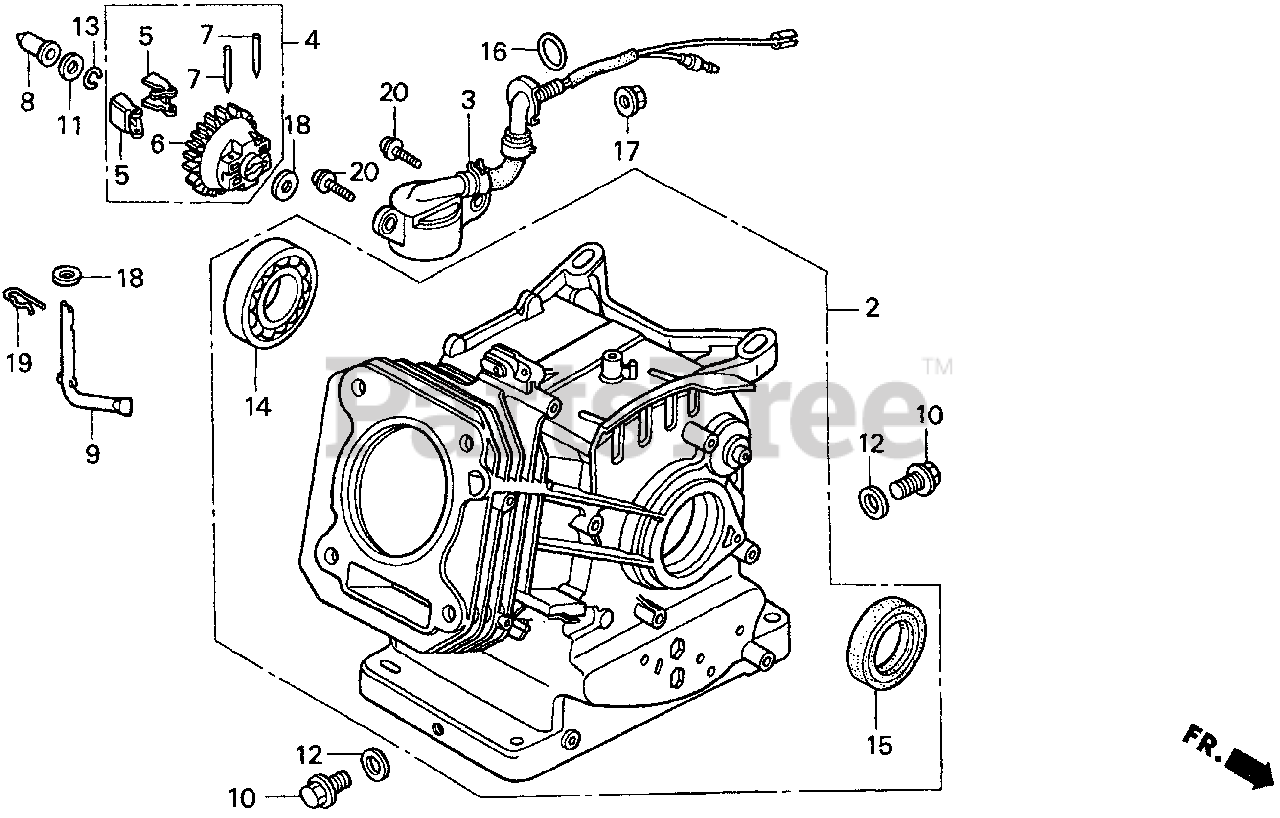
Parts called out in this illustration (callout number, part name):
2	CYLINDER ASSY. (030)
4	GOVERNOR ASSY.
5	WEIGHT, GOVERNOR
6	HOLDER, GOVERNOR WEIGHT
7	PIN, GOVERNOR WEIGHT
8	SLIDER, GOVERNOR
9	SHAFT, GOVERNOR ARM
12	BOLT, DRAIN PLUG
13	WASHER, THRUST (6MM)
14	WASHER, DRAIN PLUG (10.2MM)
15	CLIP, GOVERNOR HOLDER
16	BEARING, RADIAL BALL (62/22)
17	OIL SEAL (22X35X6)
20	WASHER, PLAIN (6MM)
21	PIN, LOCK (8MM)
